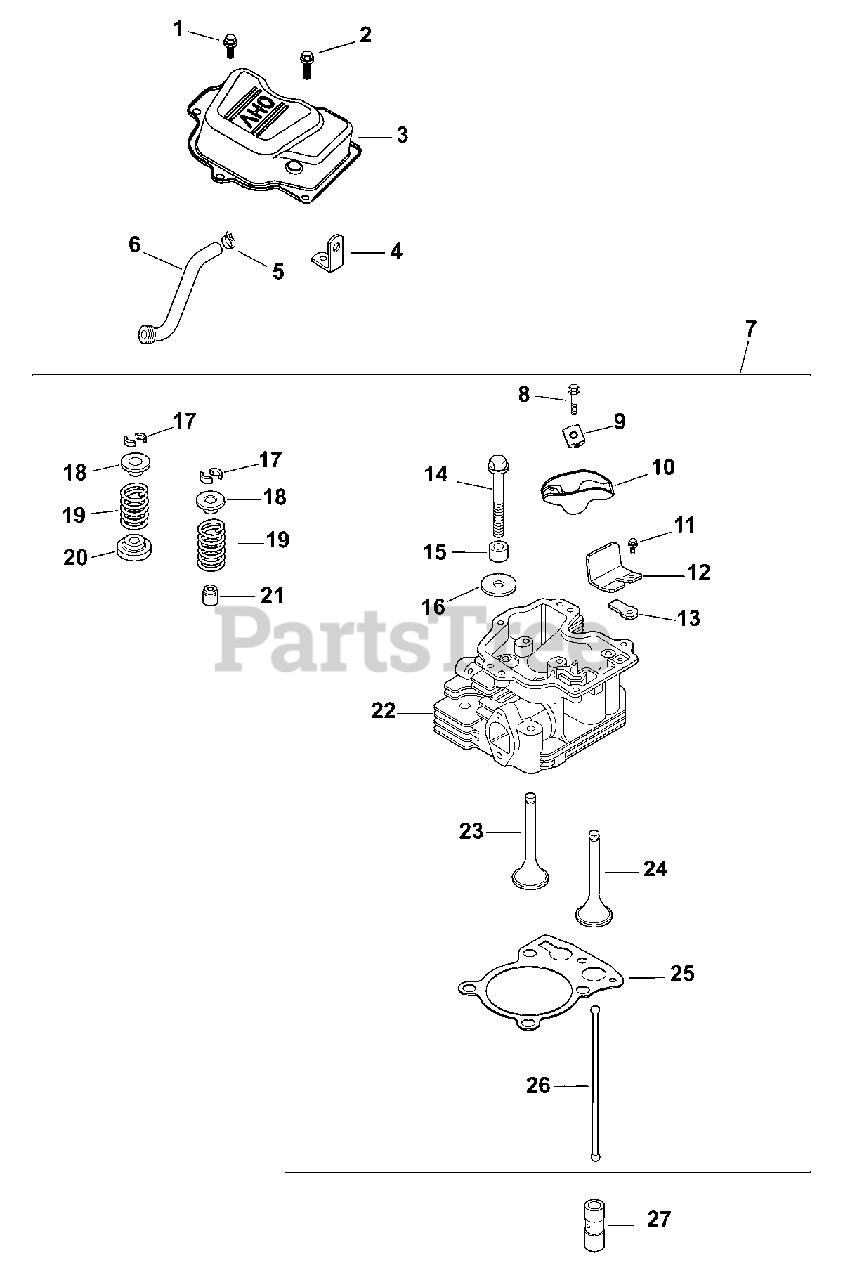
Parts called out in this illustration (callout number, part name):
1	SCREW,FLG THD FRM M6X1.0X20-(#25086396S)
2	SCREW,FLG THD FRM M6X1.0X25-(#25086395S)
3	COVER, ROCKER
5	CLAMP, HOSE (KM)-USE 25 237 31-S
6	HOSE, BREATHER - USE 12 326 27-S
7	KIT, CYLINDER HEAD
8	SCREW, FLG M6X1.0X34
9	PIVOT, ROCKER ARM
10	ARM, ROCKER
11	SCREW, FLG THD FRM M5X.8X10
12	RETAINER, REED
13	REED, BREATHER
14	SCREW, CYLINDER HEAD (M10 X 80)
15	SPACER, HEAD BOLT EXHAUST PORT
16	WASHER, FLAT 13/32"
17	KIT, RETAINER
18	RETAINER, VALVE SPRING - USE 25 173 28-S
19	SPRING, VALVE
20	RETAINER, SPRING
21	SEAL, VALVE STEM - (#2503214S)
22	KIT, HEAD, CYLINDER
23	VALVE, INTAKE
24	VALVE, EXHAUST
25	GASKET, CYLINDER HEAD
27	LIFTER, HYDRAULIC VALVE-USE 25 351 10-S
1201602-S	VALVE, EXHAUST (.25 MM)
1201702-S	VALVE, INTAKE (.25 MM)
